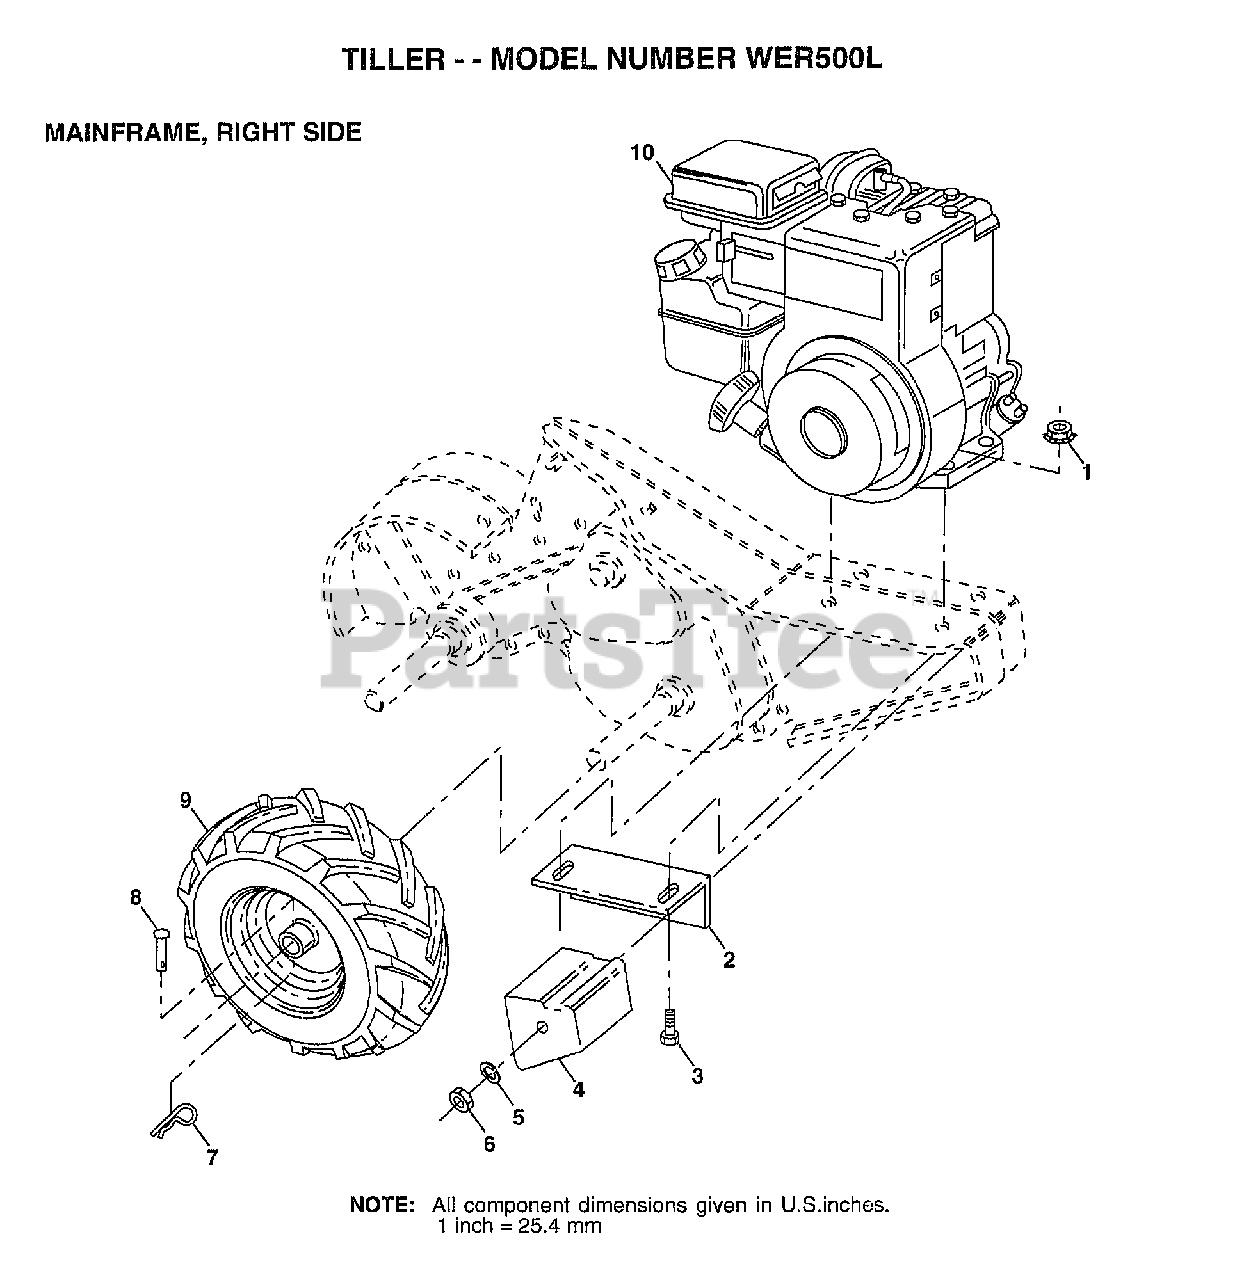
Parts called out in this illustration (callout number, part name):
2	BRACKET RH CRT
3	BOLT.HEX.5/16-1.5
4	COUNTERWEIGHT CRT
5	LOCKWASHER
6	NUT.HEX.3/8-16UNC
7	RETAINER M
8	RIVET.DRILL.1.75
9	TIRE.CHV.13X5.0-6
